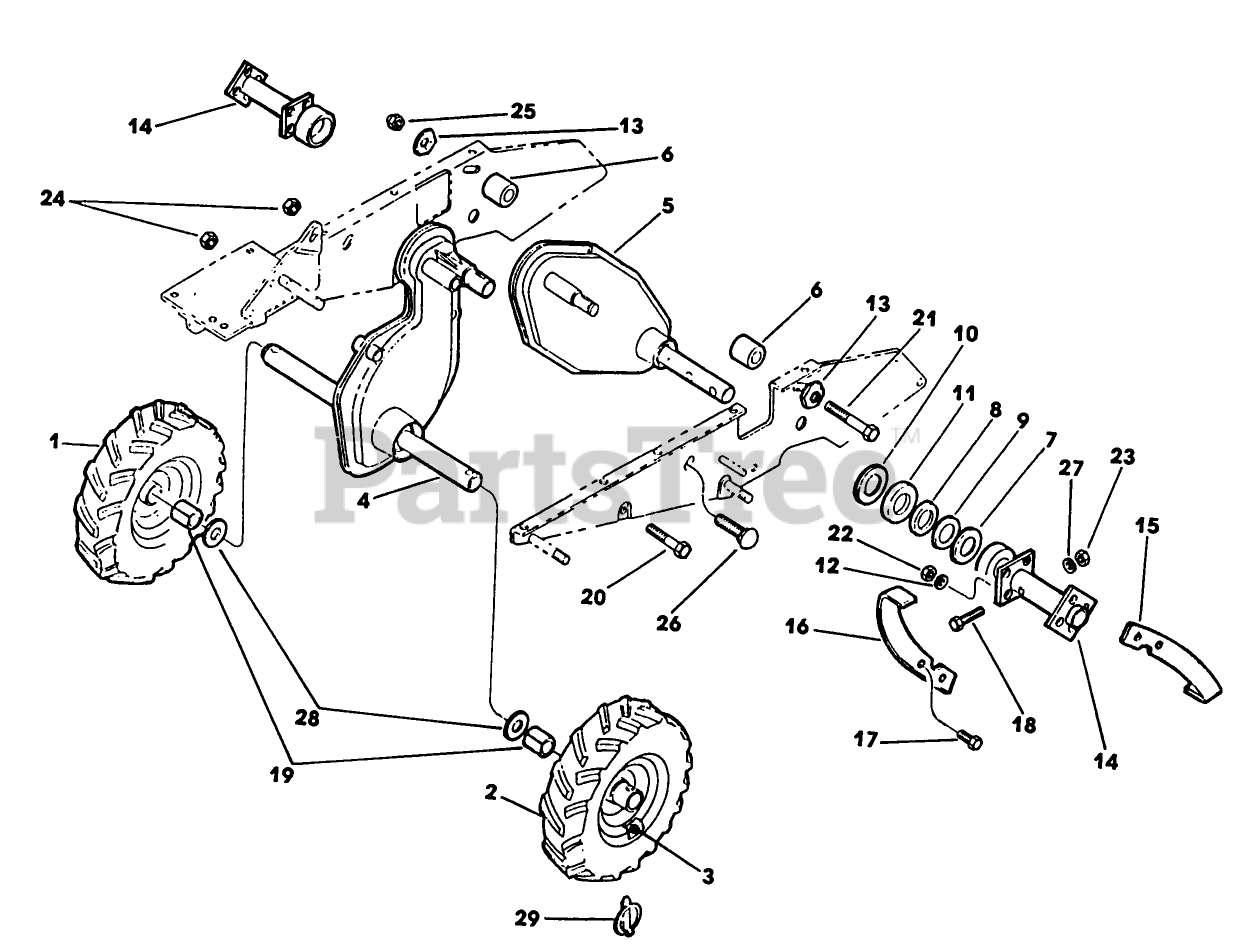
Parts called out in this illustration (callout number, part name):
8	SEAL-FELT
9	WASHER
10	WASHER BACK-UP
11	SEAL - FELT
15	TINE - RH
16	TINE - LH
22	HEX NUT
25	NUT
27	WASHER
28	WASHER
29	KILK PIN
